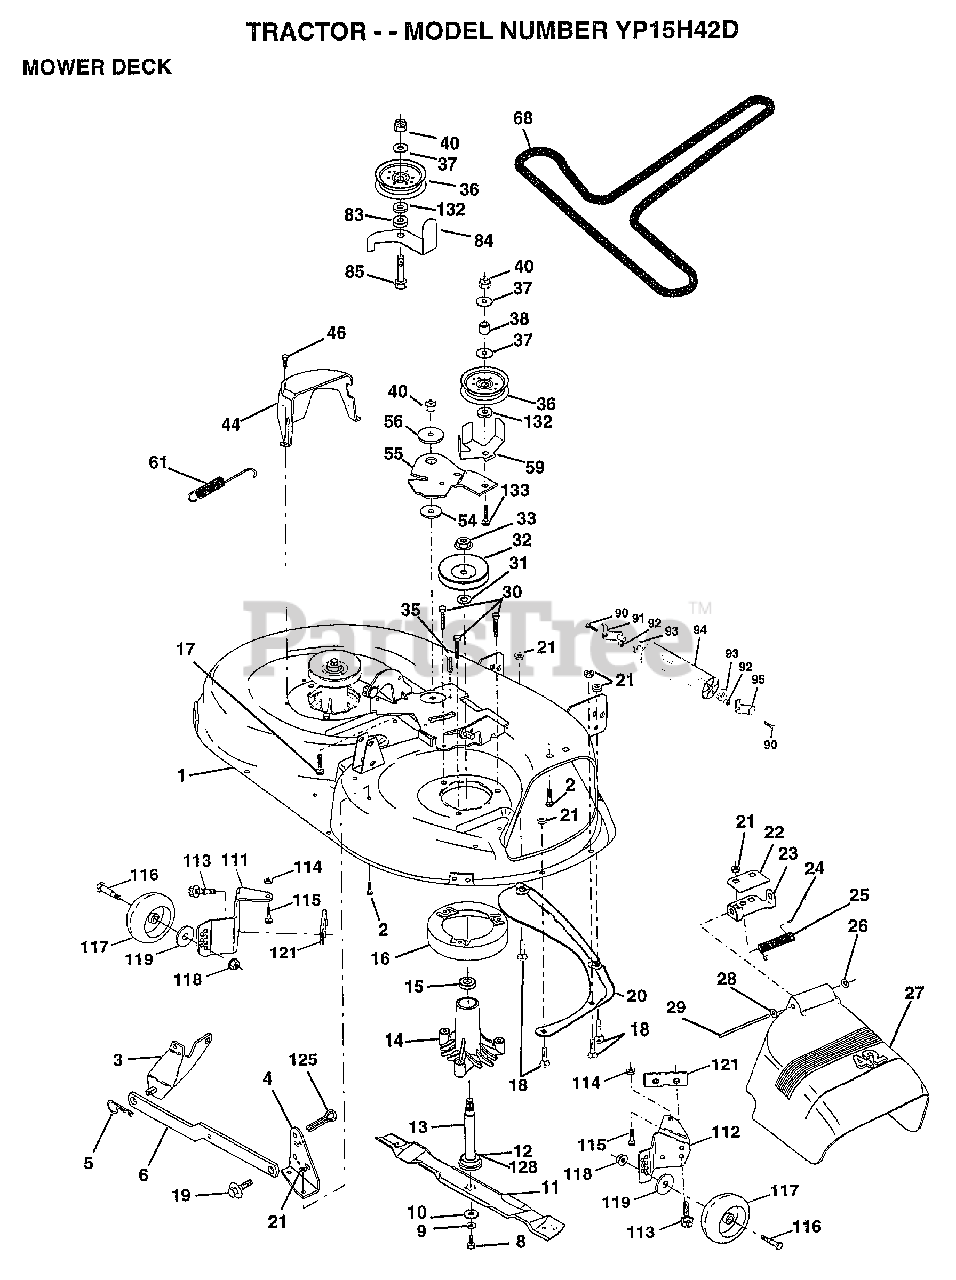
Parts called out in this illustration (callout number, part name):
1	"HOUSING ASSY.42"""
2	BOLT
3	BRKT ASM SWAY BAR
4	BRKT DECK SW BAR
8	BLADE BOLT
10	WASHER.HARD.BLADE
11	"BLADE.42"" HIPERF"
12	BEARING.BALL
14	HSG ASM MANDREL
15	BEARING
16	STRIPPER RND MWR
17	BOLT CARRIAGE
18	BOLT
19	BOLT SHD 5/16-18
20	BAFFLE VORTEX 42
22	STIFFENER BRKT
23	DEFLECTOR BRKT
24	CAP-SLEEVE LT
25	SPRING TORSION
26	NUT PUSH M
27	DEFLECTOR.SHIELD
28	WASHER
29	HINGE ROD
30	"SCREW-THD ROLL,WA"
31	WASHER
32	PULLEY.MANDREL.42
35	XMAS TREE FASTNER
36	FLAT IDLER PULLEY
37	WASHER
44	GUARD MAND LH BLK
46	SCREW.1/4-20X5/8
54	HARDENED WASHER
56	SPACER RETAINER
59	GUARD IDLER TUV
61	SPRING.EXTENSION
68	BELT.V.T-PATH
83	WASHER
84	"KEEPER-BELT,FIXED"
85	BOLT
90	BOLT
92	NUT
93	WASHER
111	BRACKET.GWHL.LH.
112	BRACKET.GWHL.RH.
113	SCREW
116	BOLT.SHOULDER
117	WHEEL GAGE DONUT
118	LOCKNUT
119	WASHER
121	BRACKET.EXTRD.GWL
125	COTTER PIN
128	WASHER.FELT.
132	WASHER GT
133	BOLT
